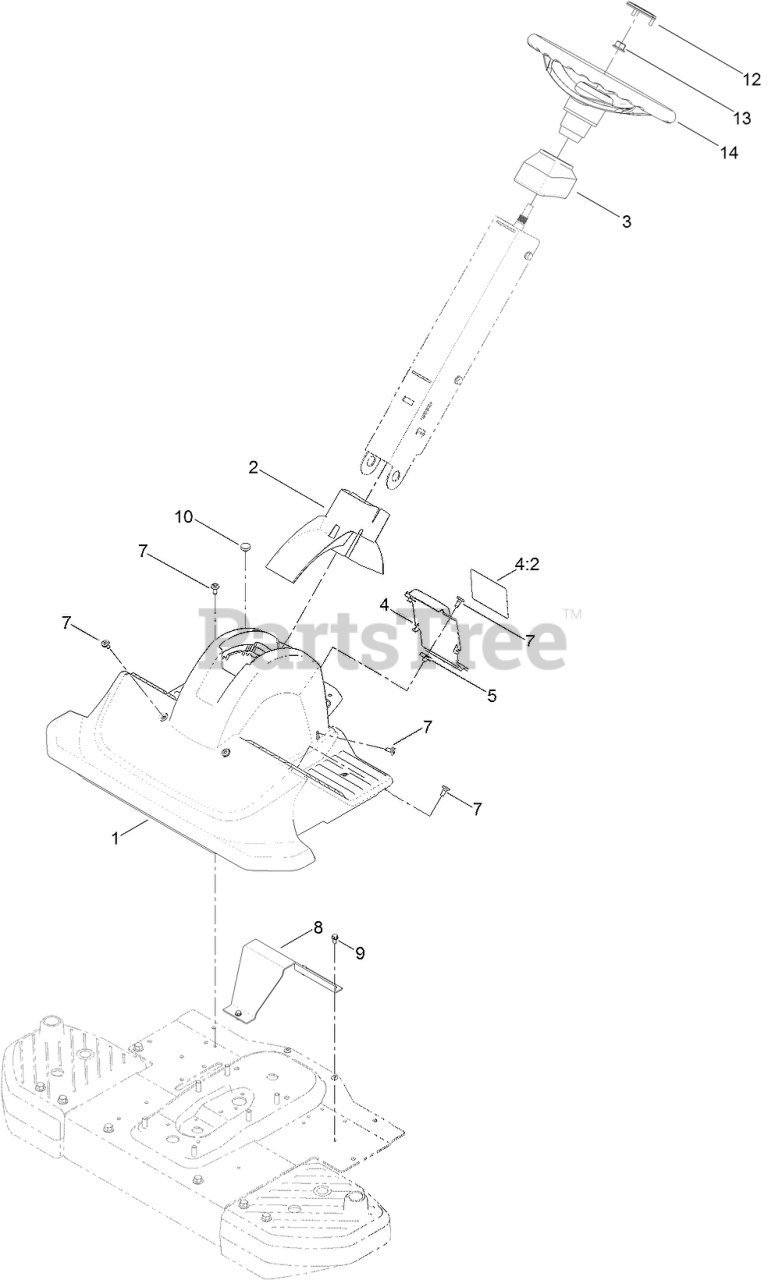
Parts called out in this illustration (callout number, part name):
1	SHROUD
2	COVER-PIVOT, COLUMN
3	CAP-COLUMN
4	REAR COVER AND DECAL ASM
4:2	DECAL-DANGER
7	SCREW-SHOULDER
8	SUPPORT-FOOTREST
9	SCREW-HWH
10	BUMPER
12	CAP-WHEEL, STEERING
13	NUT-LOCK
14	WHEEL-STEERING
